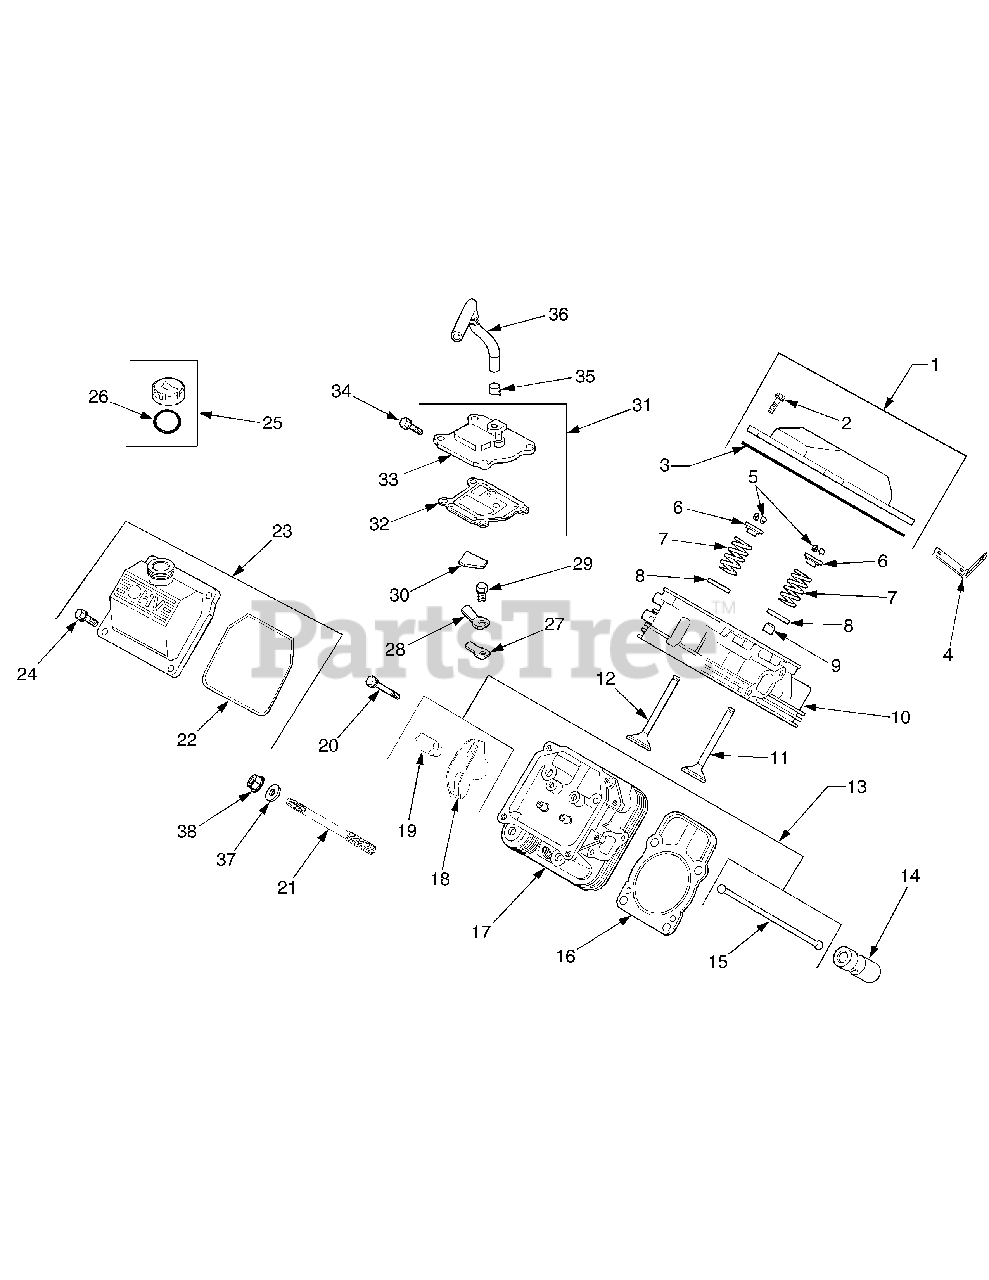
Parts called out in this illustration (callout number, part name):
1	Kit, Valve Cover (Includes 2-3) ...
2	Screw, Hx. Flng, M6 x 1.0 x 30 ...
3	O-Ring, Valve Cover
4	Strap, Lifting
5	Kit, Retainer
6	Cap, Valve Spring
7	Spring, Valve
8	Retainer, Spring
9	Seal, Valve Stem
10	Head Assembly, #1 Cylinder
11	Valve, Intake (Std.)
11	Valve, Intake (.25mm)
12	Valve, Exhaust (Std.)
12	Valve, Exhaust (.25mm)
13	Kit, Valve Train (Includes 15,18,19)
14	Lifter, Valve
16	Kit, Gasket, Cylinder Head
17	Head Assembly, #2 Cylinder
19	Pivot, Rocker Arm
20	Screw, Hex Flange M6 x 1 x 34 ..
21	Stud, Cyl. Hd.
22	O-Ring, Valve Cover
23	Cover, Valve - Oil Fill (Includes 22 and 24)
24	Screw, Hx. Flng, M6 x 1.0 x 30 ...
25	Cap Assembly, Oil Fill (Includes 26)
27	Reed, Breather
28	Retainer, Breather Reed
29	Screw, Hex Flange M5 x 0.8 x 10
30	Filter, Breather
31	Kit, Breather (Includes 32, 33)
32	Gasket, Breather
33	Cover, Breather
34	Screw, Hex Flange M6 x 1.0 x 20
35	Clamp, Breather
36	Hose, Breather
37	Washer, Flat, 8mm
38	Nut, Hex Flange, M8 x 1.25
